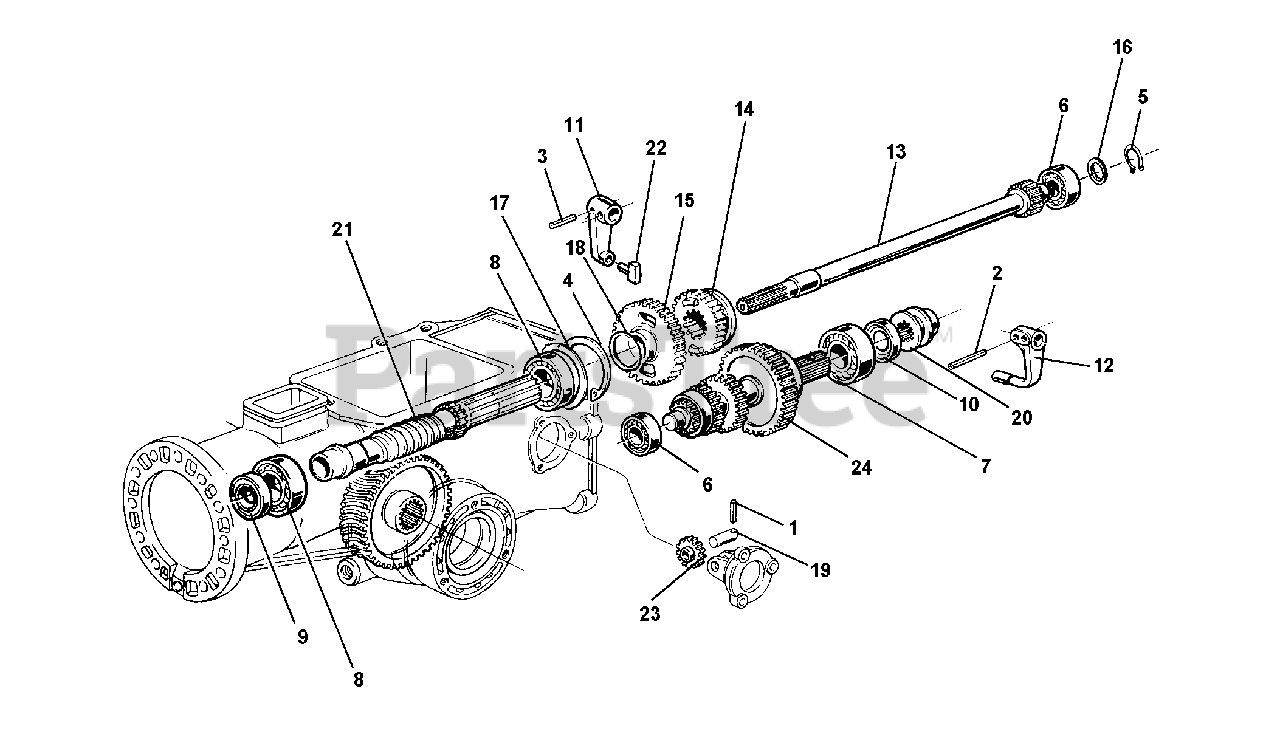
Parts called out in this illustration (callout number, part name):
1	PIN, LOCKING 2.5 X 22 DIN 1481
2	LOCKING PIN 4 X 20 SPIRAL
3	LOCKING PIN 4 X 24 SPIRAL
4	CIRCLIP, INTERN D-52
6	BEARING 15 X 35 X 11 6202
7	BEARING 20 X 47 X 14 6204
8	BEARING 25 X 52 X 15 6205
9	SEAL, OIL 15 X 40 X 10 STANDARD
10	SEAL, OIL 20 X 35 X 7 STANDARD
11	LEVER, SPEED CHG SLDG GR
12	SLIDE LEVER
13	CLUTCH SHAFT
14	SLIDING GEAR S.C.
15	GEAR, I SPEED
16	WASHER 15.1 X 25 X 2
18	WASHER 25 X 32 X 2 C-72
23	REVERSE SPEED GEAR
24	P.T.O. SHAFT
